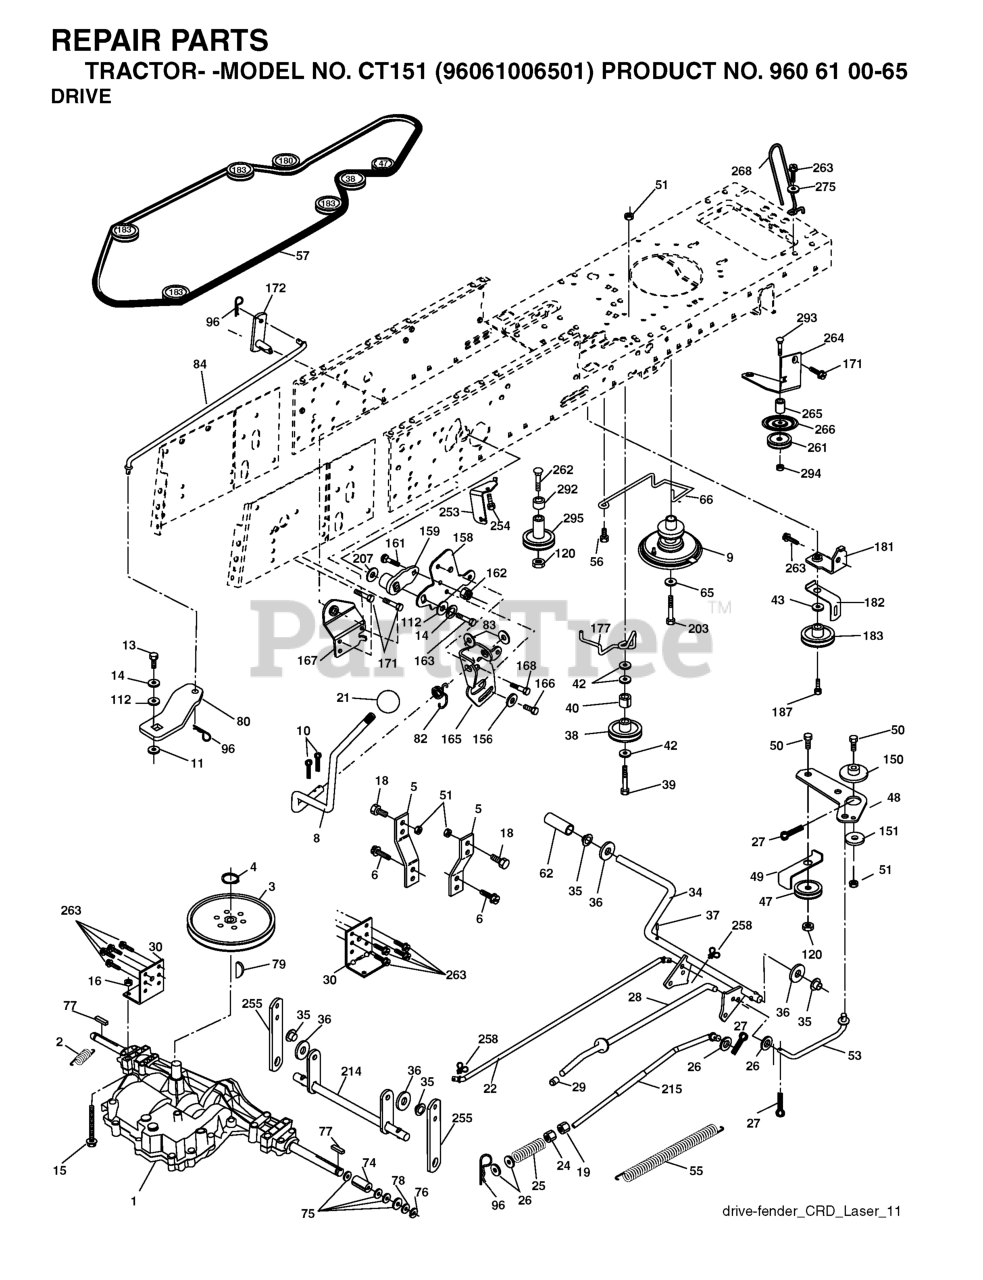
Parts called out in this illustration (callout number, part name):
2	SPRING,BRAKE RETURN
3	PULLEY
4	RETAINING RING LT
5	STRAP TORQUE
6	SCREW 5/16"
8	ROD SHIFT FENDER ADJUST LT
9	RP CLUTCH.NORAM.2002
10	PIN COTTER
11	WASH-SHFT PLT LT
13	BOLT 1/4-28X3/4
14	LOCKWASHER
15	BOLT HEX 5/16-18 GR 5
16	NUT.71038.31-18.HEX.NYLOCK
19	NUT
21	KNOB.DUCKHEAD.1/2
22	ROD
24	NUT
25	SPRING ROD LT
26	WASHER
27	COTTER PIN
28	ROD, PARKING BRAKE
29	PLUNGER CAP
30	BRKT, MOUNT TRNSAXLE
34	SHAFT, FOOT PEDAL
35	BEARING.NYLON
37	DRIVE PIN
38	PULLEY.FLAT
42	WASHER
47	IDLER PULLEY
48	BELLCRANK, CLUTCH
49	RETAIN BELT
50	BOLT.3/8-16X1.50
53	LINK.CLUTCH.7.66.2005
55	SPRING, RETURN LT
56	SCREW.3/8-16
57	V-BELT.KEV.111"
62	COVER, PEDAL (1 2)
65	LOCKWASHER
66	KEEPER BELT ENGINE
74	SPACER AXLE
77	SQUARE KEY
79	KEY STD (1373) DANA
82	SHIFT SPRING
83	WASHER
96	RETAINER M
120	NUT LOCK FLG 3/8-16 UNC
150	BUSHING.BELLCRANK.GRD.DR
151	WASHER 12/32X2X10GA
156	WASHER.SRRTD.5/16
158	BRACKET
159	RB HUB.SHIFT
161	BOLT
162	NUT.CROWNLOCK.1/4
165	RP BRACKET
166	CAPSCREW.HXHD.FLG.5/16-18X.625
167	BRACKET.SUPT.SHIFT.CRD
168	BOLT.SHOULDER.5/16-18X
172	SHAFT
181	BRACKET
182	BELT GUIDE
183	PULLEY.V-IDLER.GRND.DR
187	BOLT.5/16-18X1.25
203	BOLT.HEX.7/16-20 X 5
207	WASHER NYL
214	LEVER
254	SCREW 3/8-16X1
255	SHAFT
258	CLIP RETAINER
261	FLAT IDLER PULLEY
263	SCREW, 3/8-16X3/4
265	SPACER IDLER
266	PROTECTOR
268	GUARD MUFFLER
275	WASHER
292	SPACER
294	NUT.HEX.3/8-16
295	PULLEY IDLER COMPOSITE
